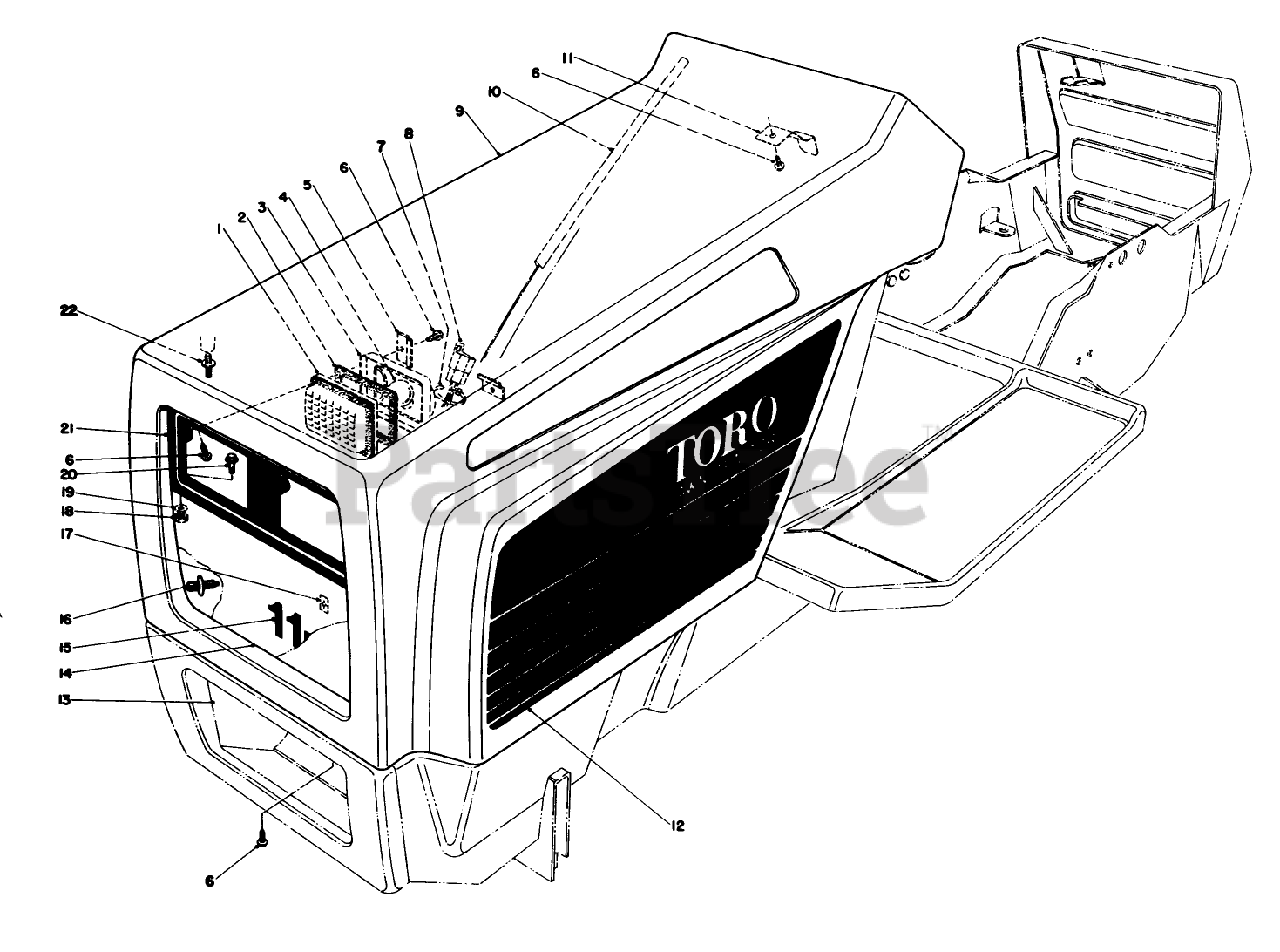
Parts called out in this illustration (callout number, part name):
1	Lens
2	Lens Gasket
3	Reflector Assembly
6	SCREW-HWHTF
7	TIE-CABLE
11	SPRING LATCH
13	LOWER GRILLE
18	NUT-LOCK, SIDE
19	WASHER-FLAT
20	SCREW-SHWH
